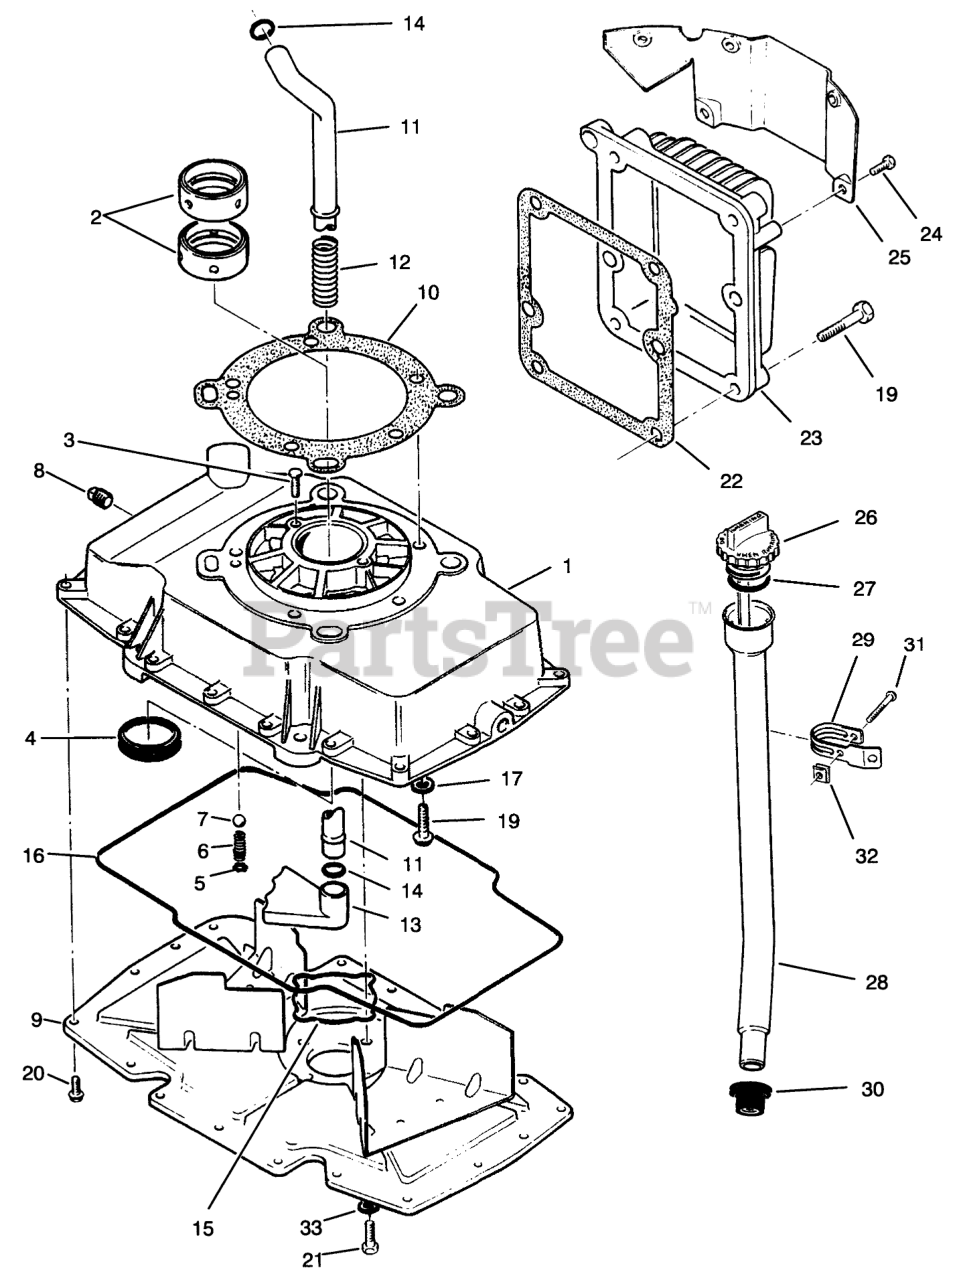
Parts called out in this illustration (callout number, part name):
1	Base-Oil (Incl. Ref. #2-7)
2	BEARING KIT (STANDARD SLEEVE)
2	BEARING KIT (.010)
3	Screw
4	OIL-SEAL
5	RETAINING-RING
6	SPRING
7	BALL-BEARING
8	Plug
9	OIL-BASE COVER ZINC
10	OIL-BASE GASKET
11	OIL-PICKUP TUBE
12	OIL-PICKUP SPRING
13	OIL-PICKUP CUP
14	O-RING
15	OIL-SEAL
16	OIL-SEAL
17	Washer
19	HEX-HEAD CAP SCREW
20	SCREW-HH
21	SCREW-HWH
22	Gasket
23	OIL-COOLER
24	HEX HD CAPSCREW
25	OIL-COOLER BAFFLE
26	Indicator-Oil Level (Incl. Ref. #27)
27	SEAL 0-RING
28	OIL-FILL TUBE (ZINC)
29	SUPPORT-BRKT (ZINC)
30	Seal
31	Screw
32	Nut
33	WASHER
